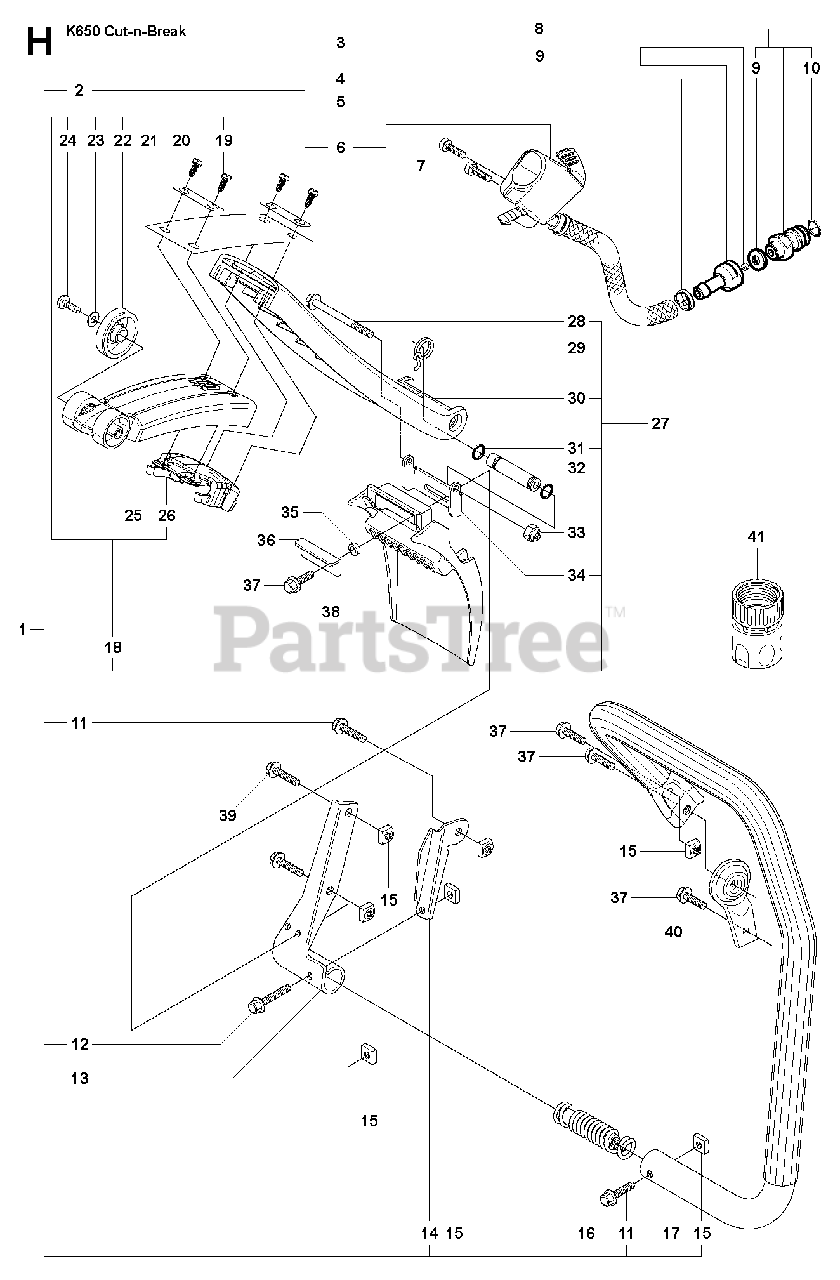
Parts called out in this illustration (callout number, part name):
1	HANDLEIncl. 2, 11 - 17
4	HOSE CLAMP
8	MUFFLER ASSYIncl. 9,10
10	O-RING
11	SCREW EHHFM
18	SPRAY GUARDIncl. 19-26
19	SCREW CRPANT
27	SPRAY GUARDIncl. 18, 28 - 34
40	ANTIVIBRATION ELEMENT
